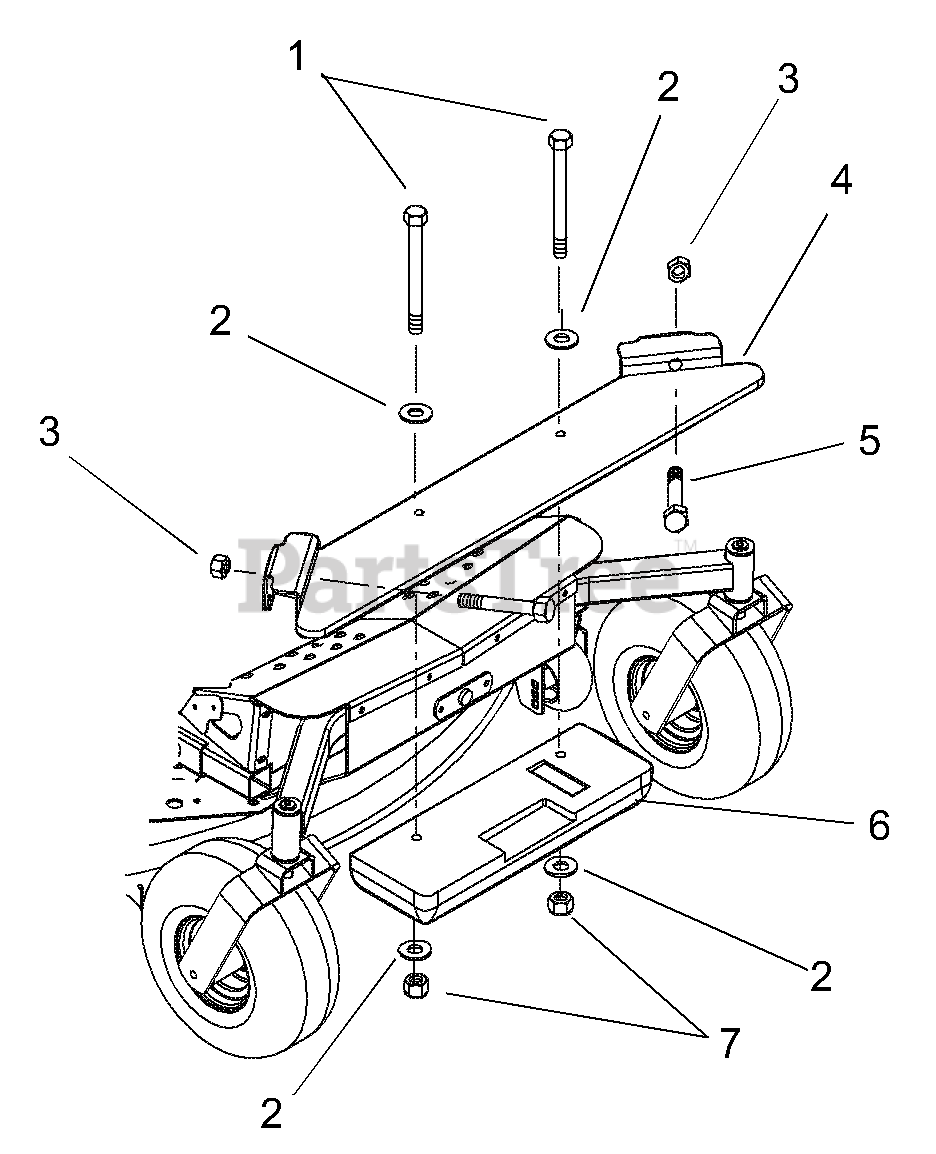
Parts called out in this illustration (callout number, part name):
1	1/2"-13 x 3-1/2" Hex Bolt
2	1/2" x 1" x 1/16" Flat Steel Washer
3	3/8"-16 Nylon Lock Nut
4	Weight Plate
5	3/8"-16 x 3" Grade 5 Hex Bolt
6	Cast Iron Weight
7	1/2"-13 Center Lock Nut
